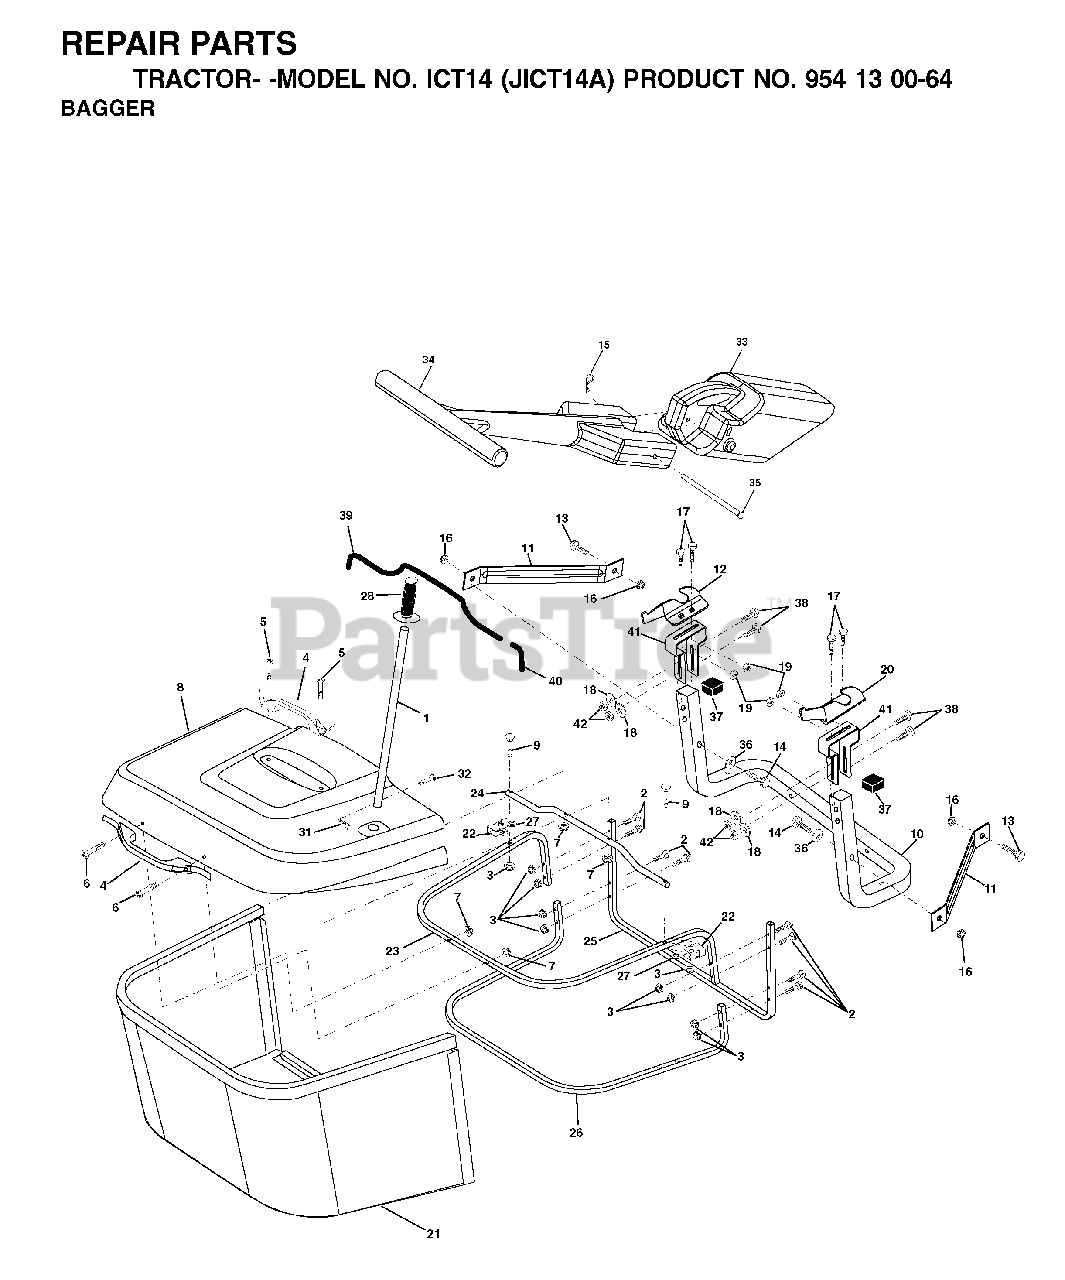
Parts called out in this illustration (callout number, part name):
1	TUBE HANDLE BAGGER
3	NUT T
5	SCREW.PAN.HEAD
10	TUBE
11	BRACKET
14	BOLT
15	RETAINER-SPRNG RB
16	NUT LOCK FLG 3/8-16 UNC
17	BOLT
18	WASHER M
19	NUT LOCK HEX FLANGE 5/16-18
20	BRACKET
21	BAG
22	BRACKET
23	TUBE
24	TUBE
26	TUBE
31	RETAINER M
32	RIVET,DRILLED
33	PLUG
35	PIN
36	WASHER
38	BOLT.5/16-18X2.5
39	TRIM
40	TRIM
41	BRKT, BAGGER
42	NUT.71038.31-18.HEX.NYLOCK
